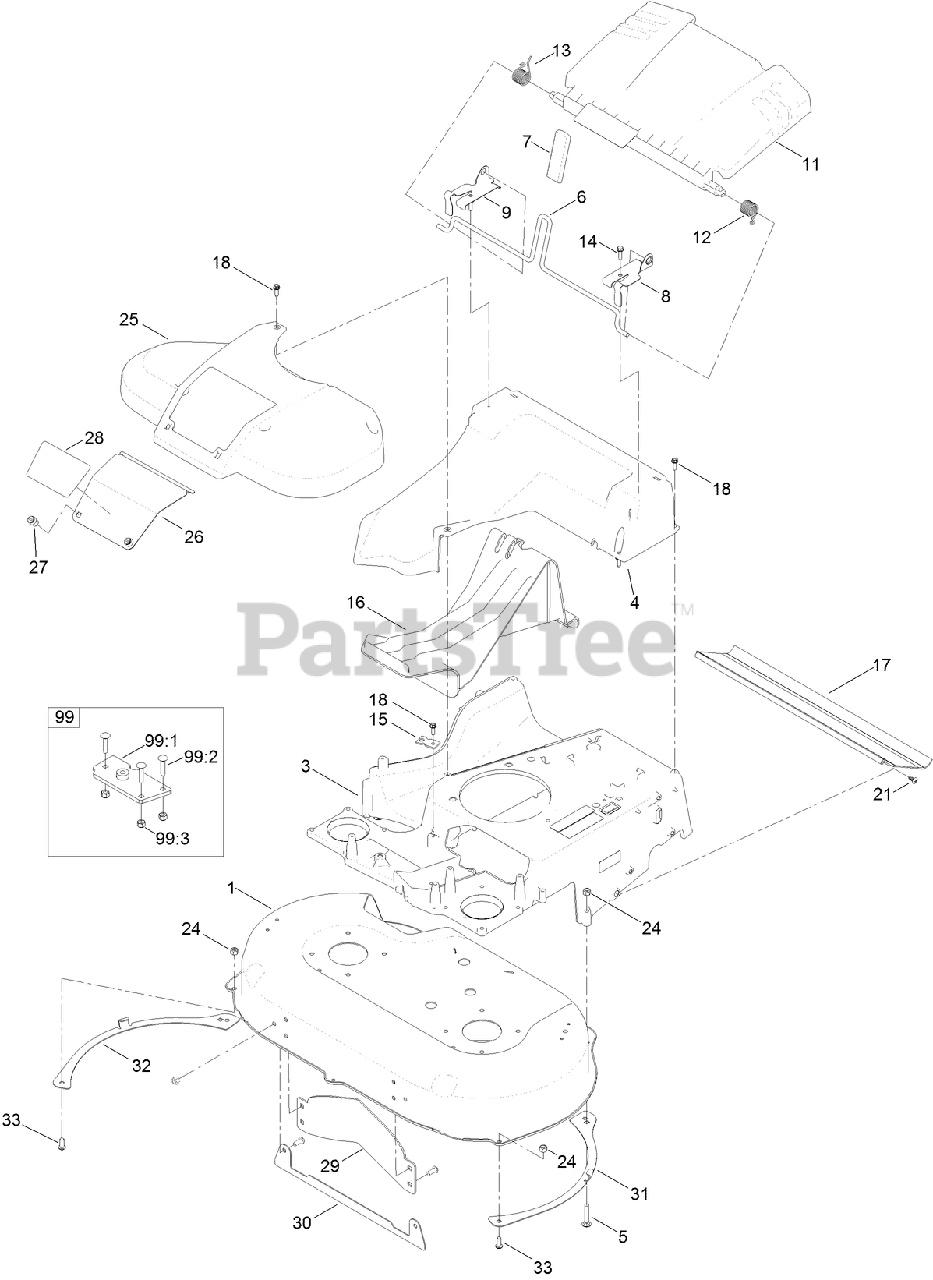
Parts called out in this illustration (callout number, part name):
1	HOUSING ASM
5	BOLT-CAR
6	ROD-RELEASE, HANDLE
7	GRIP-LEVER
8	BRACKET-DOOR, LH
9	BRACKET-DOOR, RH
11	REAR DEFLECTOR ASM
12	SPRING-TORSION
13	SPRING-TORSION
14	SCREW-HWH
16	PLUG-MULCH
17	SHIELD-TRAILING
18	SCREW-HWHTF
21	SCREW-PTH
24	NUT-LOCK, NI
25	COVER-BELT
26	DOOR-ACCESS
27	FASTENER
28	DECAL-ACCESS PANEL
29	BAFFLE-CONTROL
30	PLATE-DECK
33	SCREW-HSBH
99	FRAME PLATE KIT
99:1	PLATE-FRAME
99:2	SCREW-CARR
99:3	NUT-LOCK, NI
